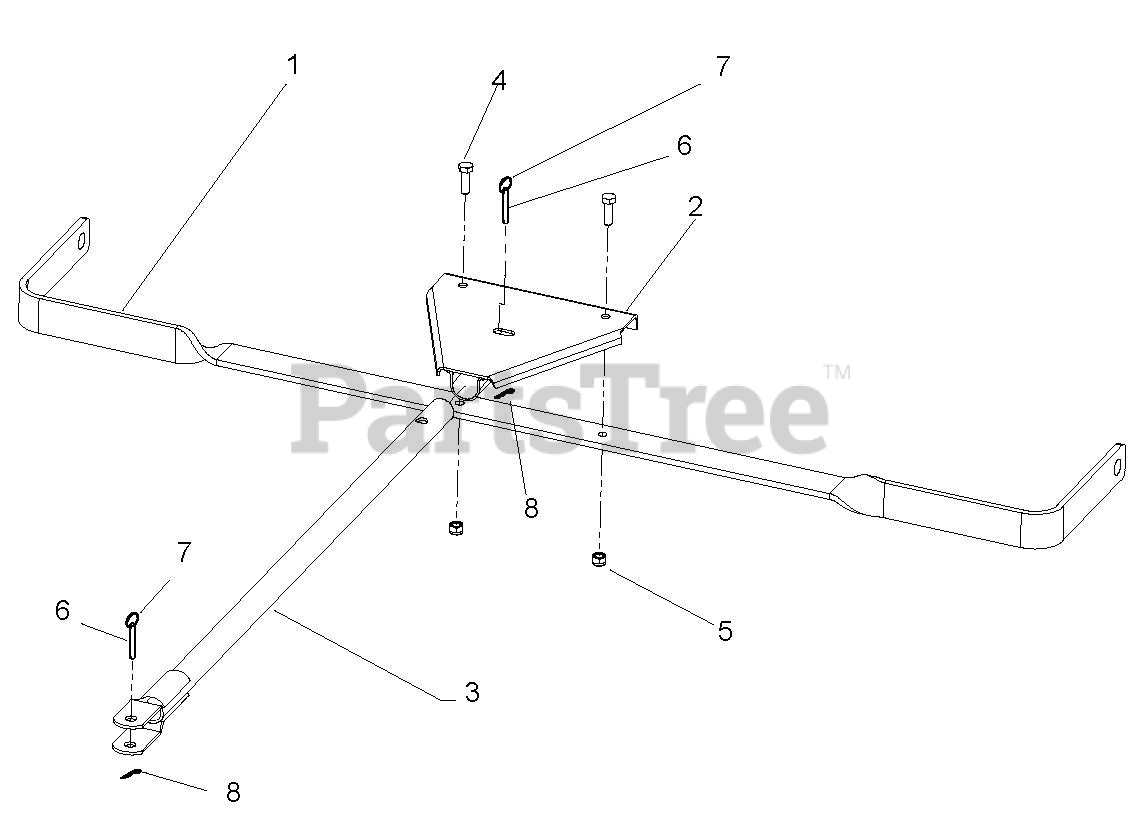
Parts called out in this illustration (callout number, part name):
2	Hitch Plate Weldment
3	Tongue Weldment
4	Bolt, 5/16-18 x 1 Hex 5
5	Nut, 5/16-18 Nyloc
6	Pin, Hitch
7	Ring, Retaining
8	Pin, Hair Pin, .091 x 1.63
